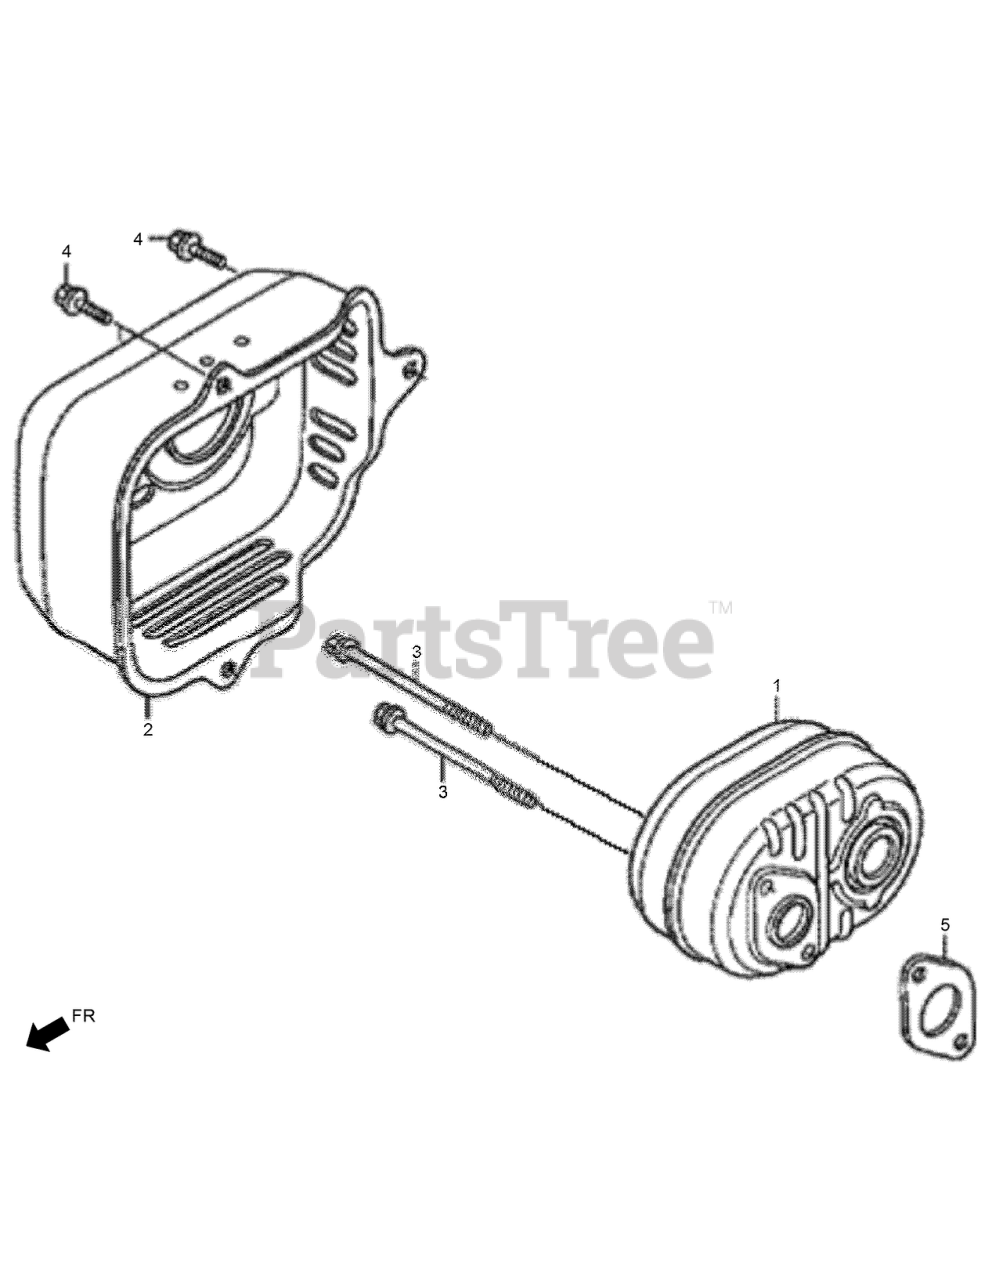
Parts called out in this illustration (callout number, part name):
1	MUFFLER
2	MUFFLER PROTECTOR ASM
3	BOLT-FLANGE-6X79
4	BOLT-FLANGE-6X12
5	GASKET-MUFFLER
